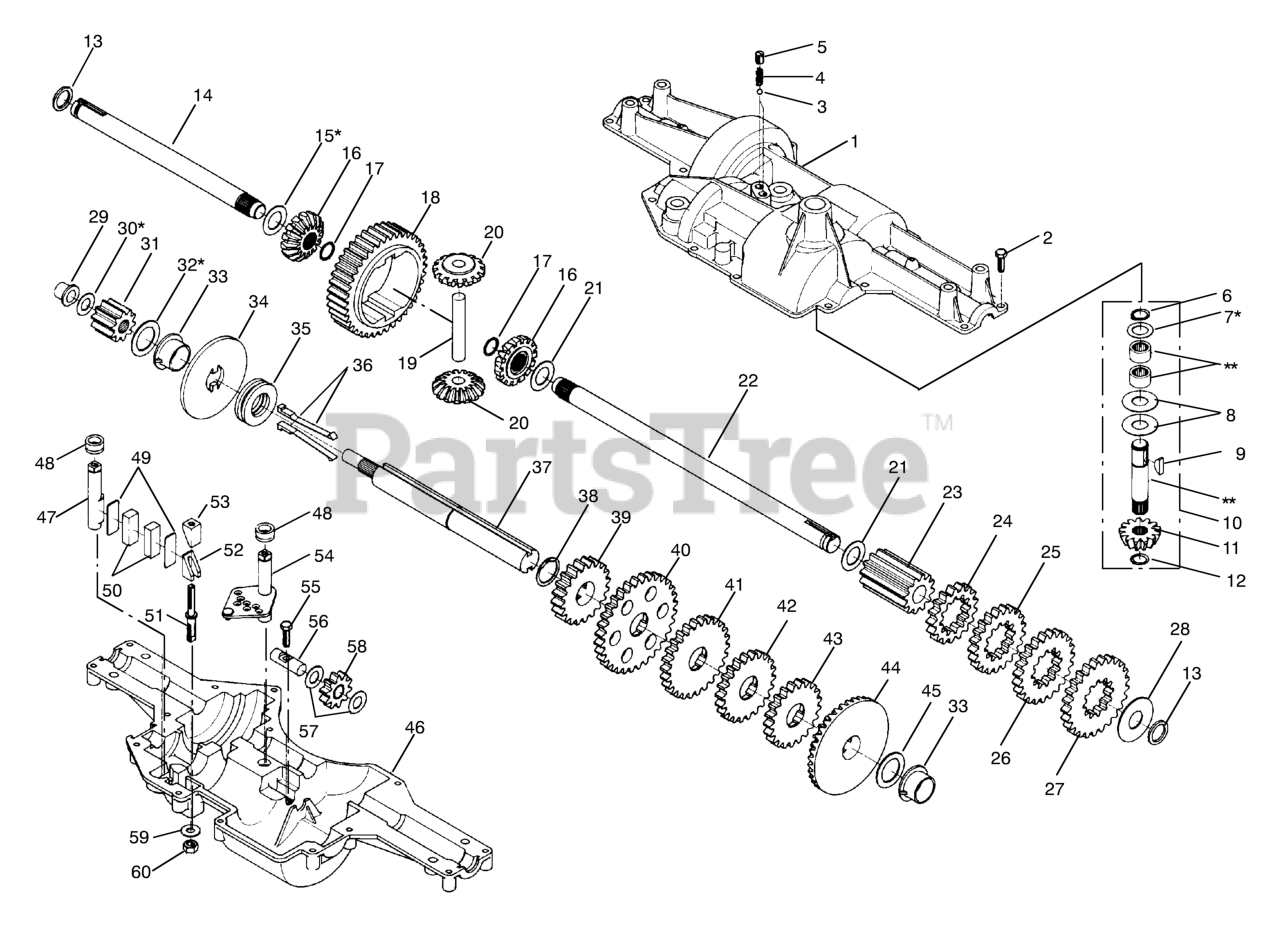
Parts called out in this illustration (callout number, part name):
1	Housing, Upper
2	Screw, Tapping 1/4-20x .734
3	Ball, Detent
4	Spring, Detent
5	Screw, Set
6	Ring, Retainer
7	Washer, Plain .632 x 1.00 x .031
7	Washer, Plain .632 x 1.00 x .036
7	Washer, Plain .632 x 1.00 x .041
7	Washer, Plain .632 x 1.00 x .046
7	Washer, Plain .632 x 1.00 x .050
7	Washer, Plain .632 x 1.00 x .060
7	Washer, Plain .632 x 1.00 x .082
8	Washer, Plain .632 x 1.38 x .046
9	Key, Woodruff, #9
10	Assembly Kit, Input Shaft
11	Pinion, Bevel 13T
12	Ring, Retainer
13	Seal, Felt
14	Axle, L.H.
15	Washer, Plain .758 x 1.25 x .020
15	Washer, Plain .758 x 1.25 x .025
15	Washer, Plain .758 x 1.25 x .031
15	Washer, Plain .758 x 1.25 x .035
15	Washer, Plain .758 x 1.25 x .040
15	Washer, Plain .758 x 1.25 x .045
15	Washer, Plain .758 x 1.25 x .050
16	Gear, Miter - 15T
17	Ring, Retainer
18	Gear, Spur - 39T
19	Shaft, Cross
20	Gear, Miter - 15T
21	Washer, Plain .758 x 1.25 x .062
22	Axle, R.H.
23	Gear, Spur - 12T
24	Gear, Spur - 17T
25	Gear, Spur - 21T
26	Gear, Spur - 23T
27	Gear, Spur - 25T
28	Washer, Plain .758 x 1.88 x .062
29	Bearing, Flange
30	Washer, Plain .505 x .942 x .010
30	Washer, Plain .505 x .942 x .015
30	Washer, Plain .505 x .942 x .020
30	Washer, Plain .505 x .942 x .026
30	Washer, Plain .505 x .942 x .030
30	Washer, Plain .505 x .942 x .040
30	Washer, Plain .505 x .942 x .060
31	Gear, Spur - 10T
32	Washer, Plain 1.01 x 1.50 x .061
32	Washer, Plain 1.01 x 1.50 x .075
32	Washer, Plain 1.01 x 1.50 x .090
33	Bearing, Flange
34	Disc, Brake
35	Collar, Clutch
36	Key, Clutch
37	Shaft, Drive
38	Ring, Retainer
39	Gear, Spur - 20T
40	Gear, Spur - 32T
41	Gear, Spur - 26T
42	Gear, Spur - 22T
43	Gear, Spur - 21T
44	Gear, Bevel, Comb. 39 & 18T
45	Washer, Plain 1.01 x 1.50 x .061
46	Housing, Lower
47	Shaft, Brake
48	U-Ring
49	Spacer
50	Puck, Friction
51	Stud, Adjustment -Brake
52	Cam, Adjustment -Slotted
53	Cam, Adjustment -Brake
54	Assembly, Shifter
55	Screw, Tap 1/4 -18 x .875
56	Shaft, Idler
57	Washer, Plain .505 x .942 x .015
58	Assembly, Gear Spur -10T
59	Washer, Plain .325 x .750 x .059
60	Locknut 5/16 -24
61	Grease
